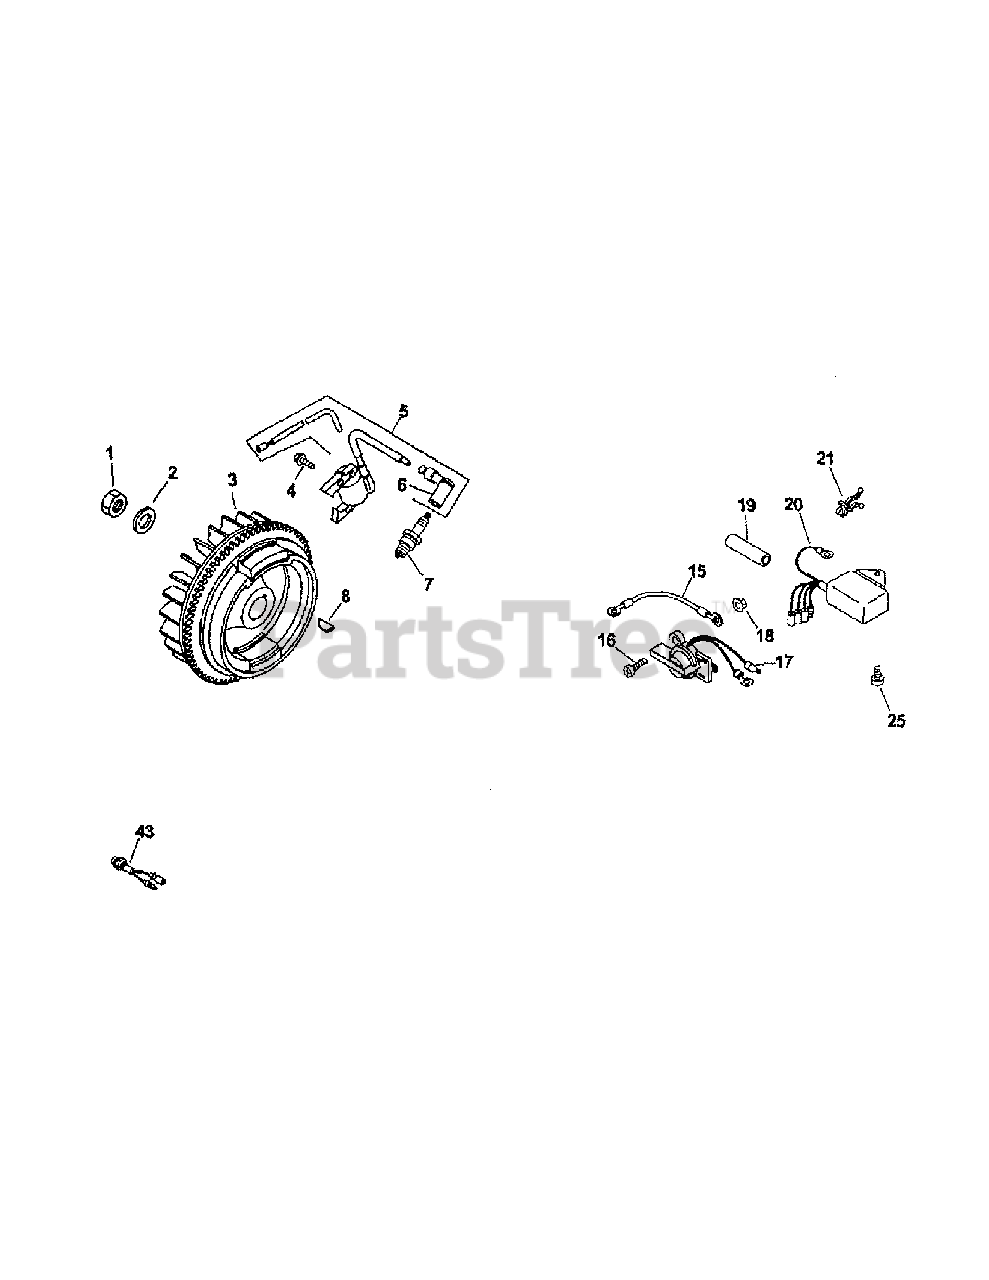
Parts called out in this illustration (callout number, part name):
1	Nut, Flywheel
2	Washer, Flywheel
3	Flywheel
5	Ignition Module
8	Key, Flywheel
19	Sleeve, Wiring
